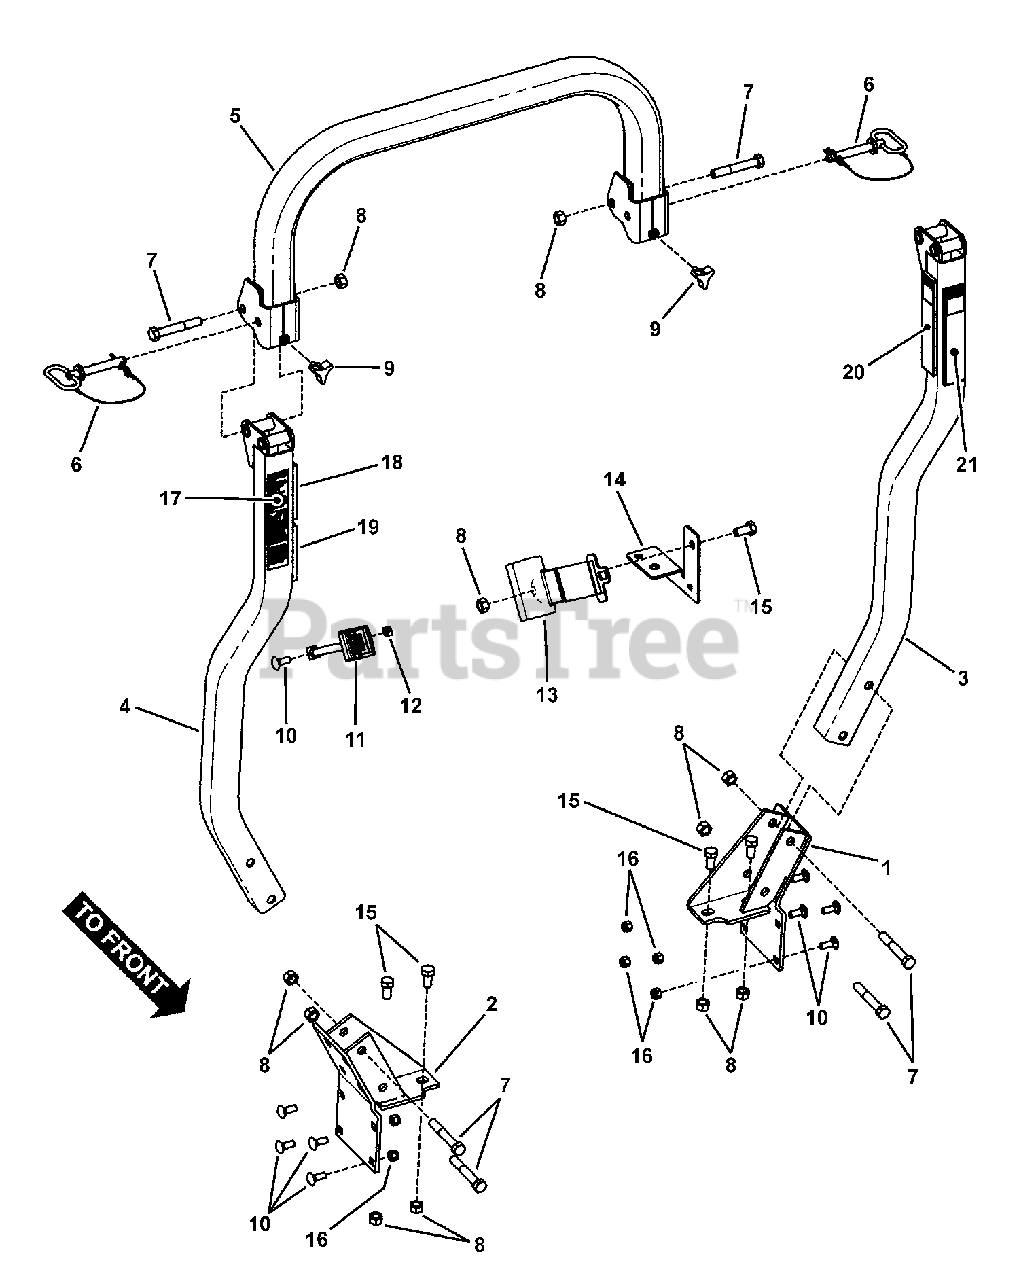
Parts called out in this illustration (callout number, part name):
1	WELDMENT, LH Socket
2	WELDMENT, RH Socket
3	WELDMENT POST, LH
4	WELDMENT POST, RH
5	TOP LOOP, Folding, CZT
6	PIN, Hinge (ROPS)
7	SCREW, 1/2-13 x 3-1/4" Hex Head Cap, GR 5
8	NUT, 1/2-13 Hex Center Lock, GR 5
9	STAR KNOB (5/16-18 thread)
10	BOLT, 3/8-16 x 1" Square Neck Carriage, GR 5
11	SEAT BELT, w/Metal Strap
12	NUT, 3/8-16 Hex Center Lock
13	RETRACTER, Seat Belt
14	BRACKET, Seat Belt, LH
15	SCREW, 1/2-13 x 1" Hex Head Cap, GR 5
16	NUT, 3/8-16 HEX NYLON LOCK
17	* DECAL, ROPS Overhang
18	* DECAL, Caution ROPS
19	* DECAL, Caution ROPS (Spanish)
20	* DECAL, Warning ROPS
21	* DECAL, Warning ROPS (Spanish)
